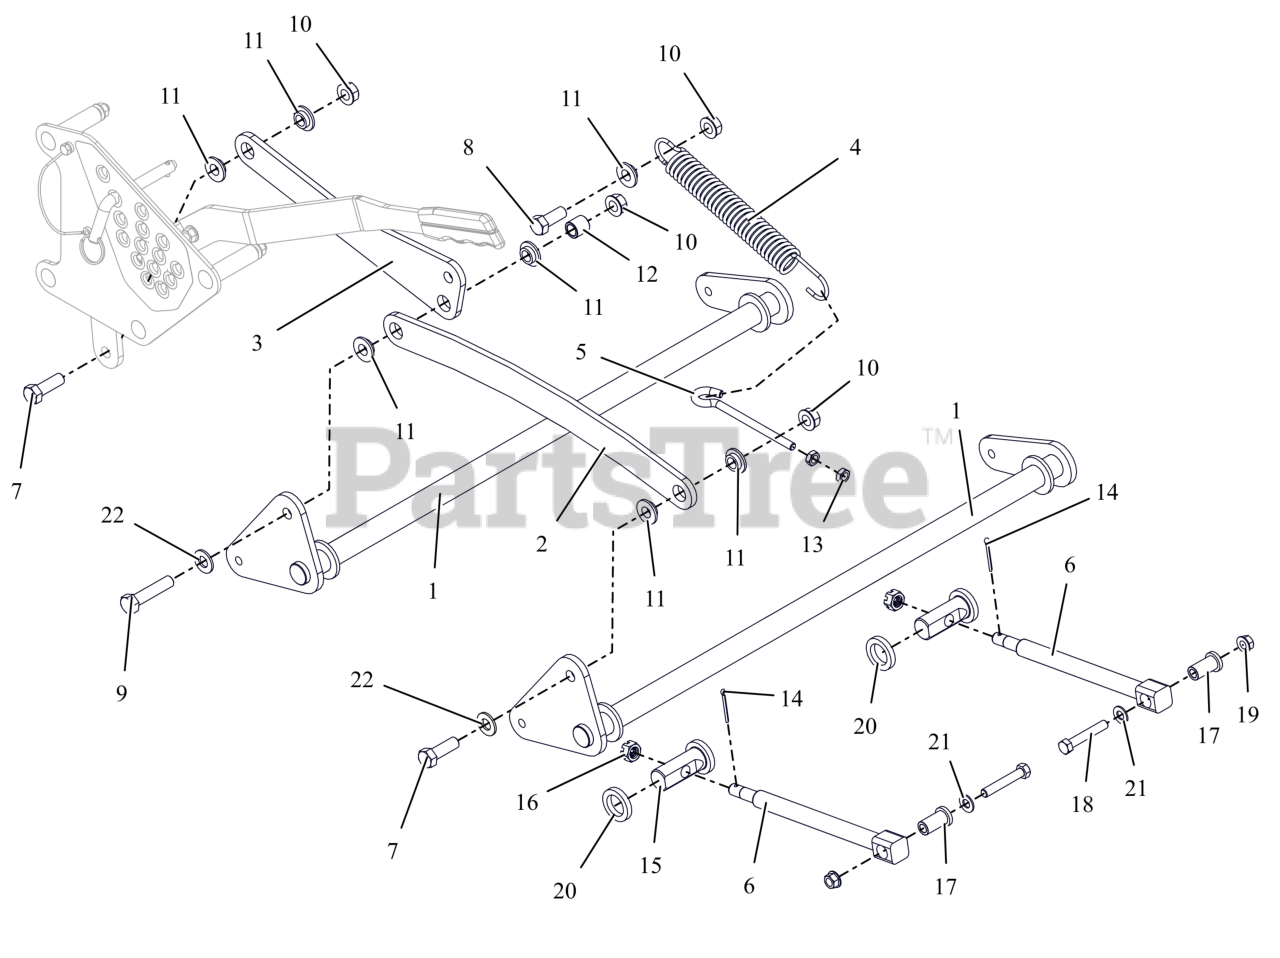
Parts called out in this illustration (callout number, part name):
1	WLDMT-48-52"DECK LFT SHFT(BLK)
2	LINK-48-52"DCK LFT CNCTNG(BLK)
3	PLT-DECK HEIGHT MECHANISM(BLK)
4	SG-TENS .162X1.25X8.25 WLD 25
5	BOLT,.38-16 X 4.25-.62 DIA EYE
6	DRAG,LINK-HD
7	BLT,HEX .50-13X1.50 G5 ZCC
8	BLT,HEX .50-13X1.25 G5 ZCC
9	BLT, HEX .50-13X2.25 G5 ZCC
10	NUT-LK-CTR-FLG .500-13 GG ZCC
11	BSHG-FLG .515X.750X.310X1.120
12	BSHG, SLV .510 X .751 X .750
13	NUT-JAM .375-16 G2 ZCC
14	PIN,CTR.12X1.25EXTPRSQCT ZC120
15	PIN, DECK LIFT
16	NUT-SL .50-13
17	SPCR, DRAG LINK
18	BLT,HEX .38-16X2.25 G5 ZCC
19	NUT-LK-CTR-FLG .375-16 GF ZCC
20	WSHR-FL-STL 1.0X1.50X.25
21	WSHR-FL-STL 0.406X0.812X0.065 UNPLATED
22	WSHR,FLT .531X1.062X.095 ZCC
